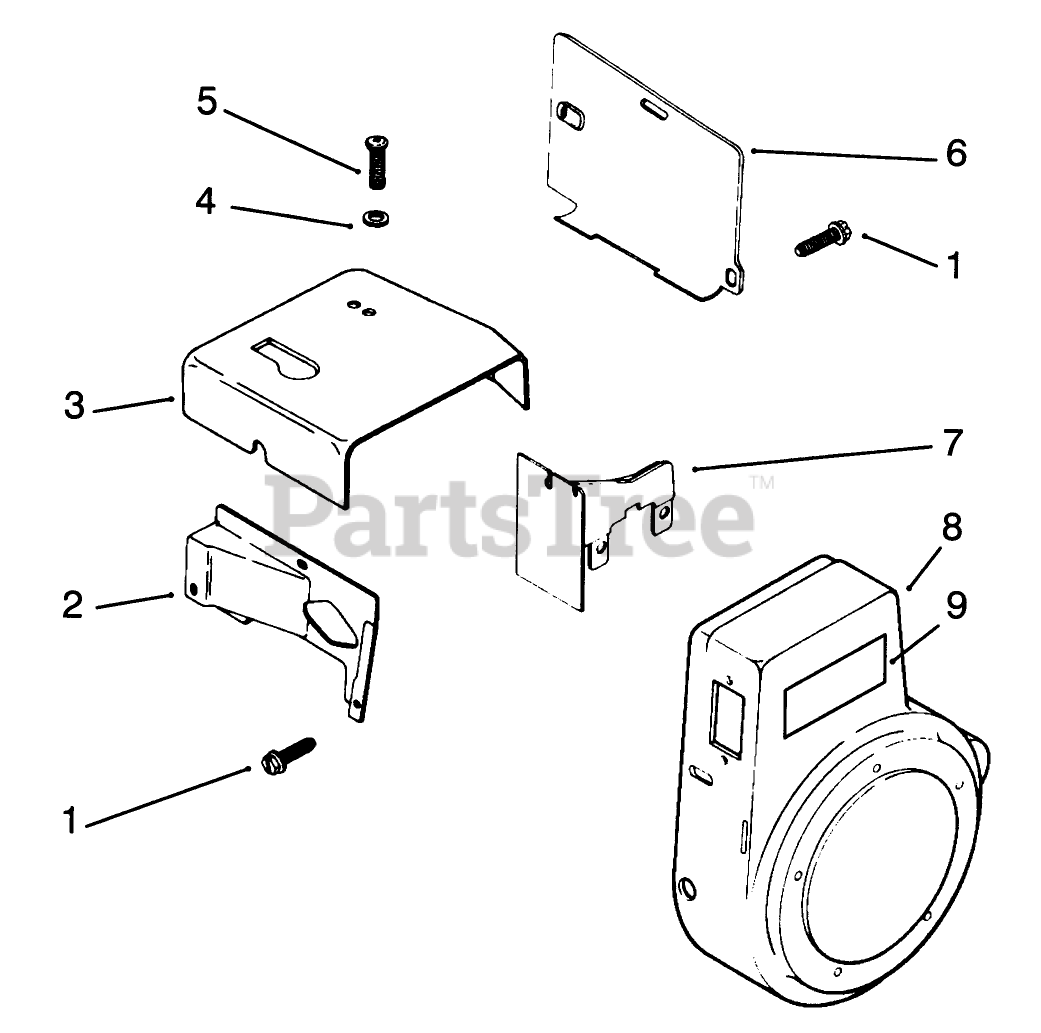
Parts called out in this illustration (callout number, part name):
1	KOHLER 52-086-11
2	KOHLER 47-063-06
3	KOHLER 45-063-08
4	KOHLER X-25-53
5	KOHLER 47-086-08
6	KOHLER 47-063-10
7	KOHLER 47-063-07
8	KOHLER 47-027-42
9	VNDR #47-113-36
